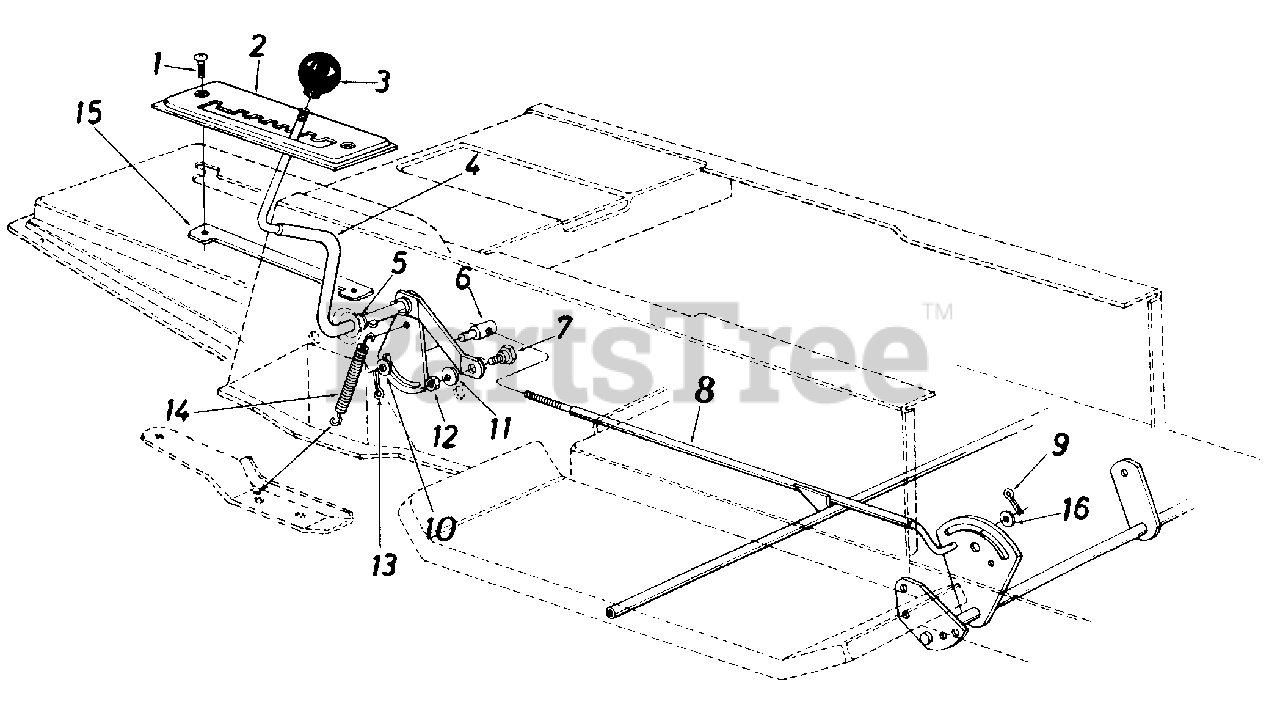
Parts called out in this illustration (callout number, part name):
1	Truss Mach. Scr. 1/4-20 x .75" Lg.
2	Speed Selector Plate 4-Speed
4	Speed Selector Cam Ass'y.
5	Flat Washer .53" I.D. x .93"
6	Ferrule 3/8-24 x .37" Dia.
7	Shoulder Bolt .435" Dia. x .1 60
8	Speed Control Rod Ass'y.
9	Cotter Pin 3/32" Dia. x .75
10	Fl-Wash. .385" I.D. x .62" O.D.
11	L-Wash. 5/16" I.D.
12	Hex Nut 5/16-18 Thd.*
13	Cotter Pin 3/32 Dia. x .75
14	Spring
15	Clamping Plate
16	Fl-Wash. .47" I.D. x .88" O.D
